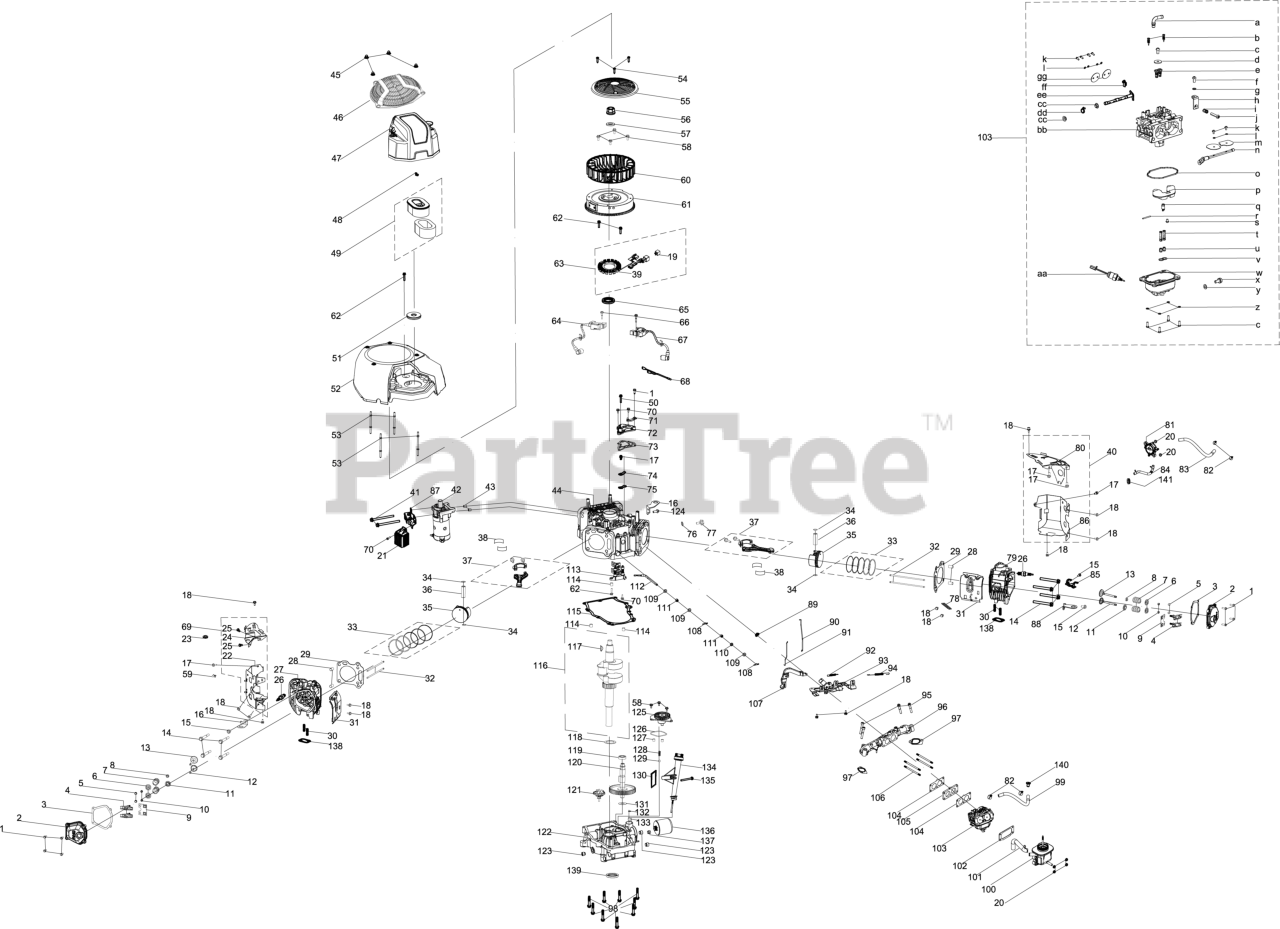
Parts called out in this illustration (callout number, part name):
1	BOLT M6x22
2	VALVE COVER
3	VALVE COVER GASKET
4	ROCKER ARM ASSEMBLY
5	EXHAUST VALVE ADJUSTER
6	VALVE SPRING SEAT
7	VALVE SPRING
8	INTAKE VALVE SEAL
9	PUSH ROD GUIDE
11	VALVE SPRING RETAINER
12	EXHAUST VALVE
13	INTAKE VALVE
14	BOLT M10x1.25x87
15	BOLT M8x16
17	BOLT M6x10
18	BOLT M6x12
21	REGULATOR ASSEMBLY
22	CYLINDER HEAD BAFFLE (LH)
23	HEAT SHIELD GROMMET
24	FLYWHEEL SHROUD (LH)
25	BOLT M6x10
26	SPARK PLUG (F6RTC/RN11YC/BPR6ES)
27	CYLINDER HEAD - LH
28	DOWEL PIN 12x20
29	CYLINDER HEAD GASKET
30	STUD M8 X 34
33	PISTON RIN SET
34	PISTON PIN SNAP RING
35	PISTON ASSEMBLY
36	PISTON PIN
37	CONNECTING ROD
38	CONNETING ROS BEARING
39	Charging Coil
40	CYLINDER HEAD SHROUD (RH)
41	BOLT M8x110
42	ELECTRIC STARTER
45	ACORN NUT M6-1
46	SHROUD FAN COVER
47	AIR FILTER COVER ASSEMBLY
49	AIR FILTER ELEMENT
50	BOLT M6x28
52	BLOWER HOUSING
54	SELF TAPPING BOLT 5.5x25
55	DEBRIS SHIELD
56	NUT M20x1.5
57	WASHER 20.5 x 5 x 40
58	BOLT M6-1 x 18
59	WIRE SUPPORT CLAMP
60	COOLING FAN
62	BOLT M6x25
63	Charging Coil
64	IGNITION MODULE (LH)
65	OIL SEAL 38 x 58 x 8
66	BOLT M6x30
67	IGNITION MODULE (RH)
69	CYLINDER HEAD BAFFLE (LH)
70	BOLT M6x16
71	FLYWHEEL OUTLET SHIELD
72	BEATHER COVER
73	BREATHER COVER GASKET
74	BREATHER REED BRACKET
75	BREATHER REED ASSEMBLY
76	WASHER 20.5X1.5X18
77	BOLT M10x1x10
79	CYLINDER HEAD - RH
80	FLYWHEEL SHROUD (RH)
81	FUEL PUMP
82	CARBURETOR HOSE CLAMP
83	FUEL HOSE
85	MOUNTING BRACKET
86	CYLINDER HEAD BAFFLE (RH)
87	STARTER RELAY SUPPORT
89	CHOKE LINKAGE LOCK CLAMP
90	THROTTLE LINKAGE
91	CHOKE LEVER
92	GOVERNOR SPRING
93	GOVERNOR GEAR BRACKET
94	GOVERNOR SPRING
95	BOLT M8x50
96	INTAKE MANIFOLD
97	INTAKE MANIFOLD GASKET 9Q78
98	BOLT M8x48
99	FUEL LINE 6.3 x 12.5 x 470
100	INTAKE MANIFOLD
101	BREATHER HOSE
102	AIR FILTER HOUSING GASKET
103	CARBURETOR
104	CARBURETOR GASKET
105	INSULATOR
106	STUD M6-1 X 105
107	GOVERNOR LEVER
108	GOVERNOR SHAFT CLIP
109	FLAT WASHER 8.5X15.8X2
110	GOVERNOR SEAL
111	NEEDLE BEARING 8X12X10
112	GOVERNOR ARM ROD
113	ROACKER ARM
115	CRANKCASE GASKET
116	CRANKSHAFT ASSEMBLY
117	WOODRUFF KEY
118	WASHER - 38.5X1.0X54
119	CAMSHAFT BEARING
120	CAMSHAFT ASSEMBLY
121	GOVERNOR GEAR
122	CRANKCASE COVER
124	BOLT M8x20
125	OIL PUMP ASSEMBLY
126	OIL PUMP GASKET
128	OIL PUMP SPRING
129	OIL PUMP STEEL BALL
130	OIL PUMP SCREEN
131	THRUST WASHER 17.4X25.9X1.0
132	O-RING 13.2X2.65
133	CRANKCASE OIL PASSAGE PIN
135	BOLT M6x55
136	ENGINE OIL FILTER
137	OIL FILTER ADAPTER
138	EXHAUST GASKET
139	OIL SEAL 38 x 58 x 8
